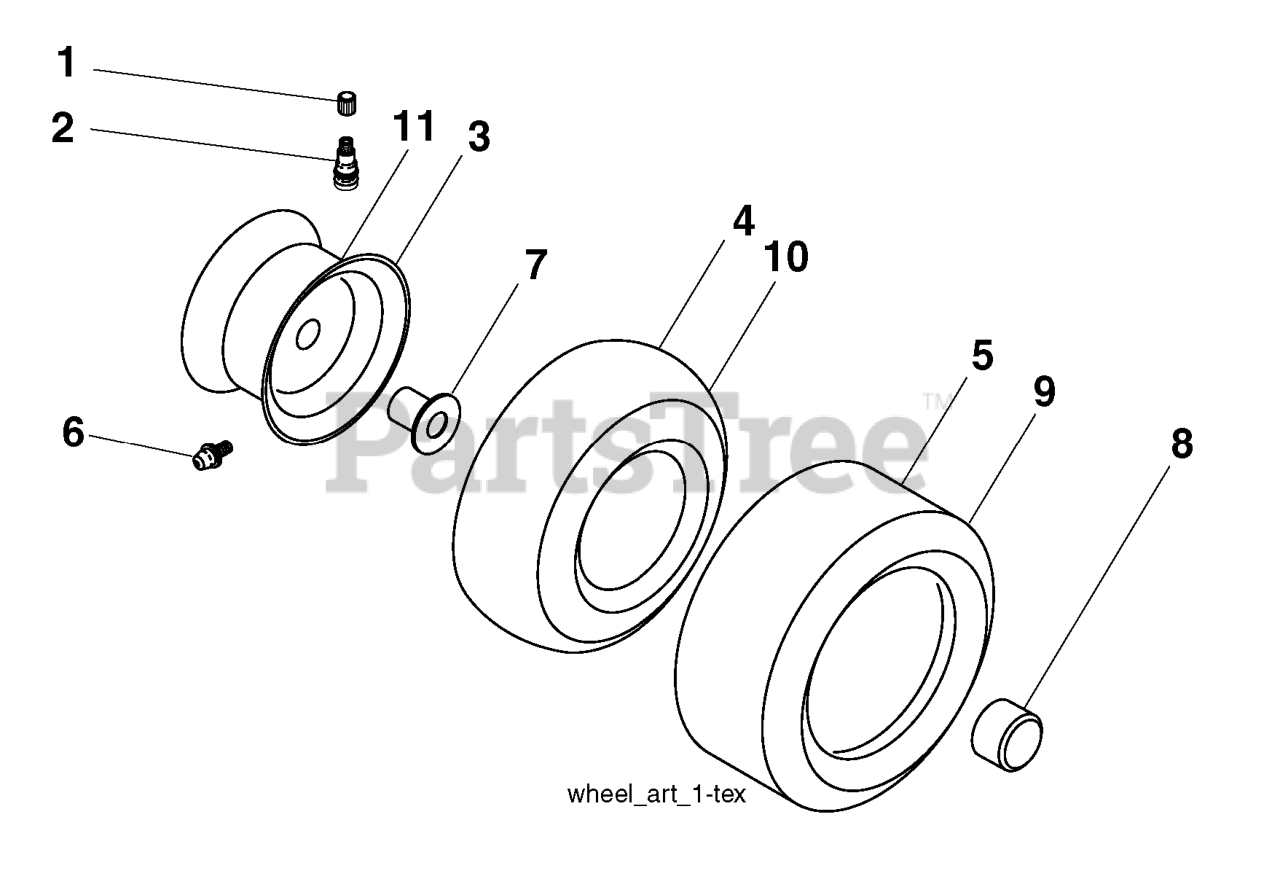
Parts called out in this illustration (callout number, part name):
2	VALVE STEM LT
3	RIM ASM 6" FRONT SILVER
4	TUBE.5.3/4.5/6
5	TIRE HEAVY DUTY
6	FITTING LT
7	BEARING T
8	CAP, AXLE BLK
9	TIRE.18X9.5-8 TURF SAVER
10	TUBE
11	RIM ASM 8" REAR SILVER
